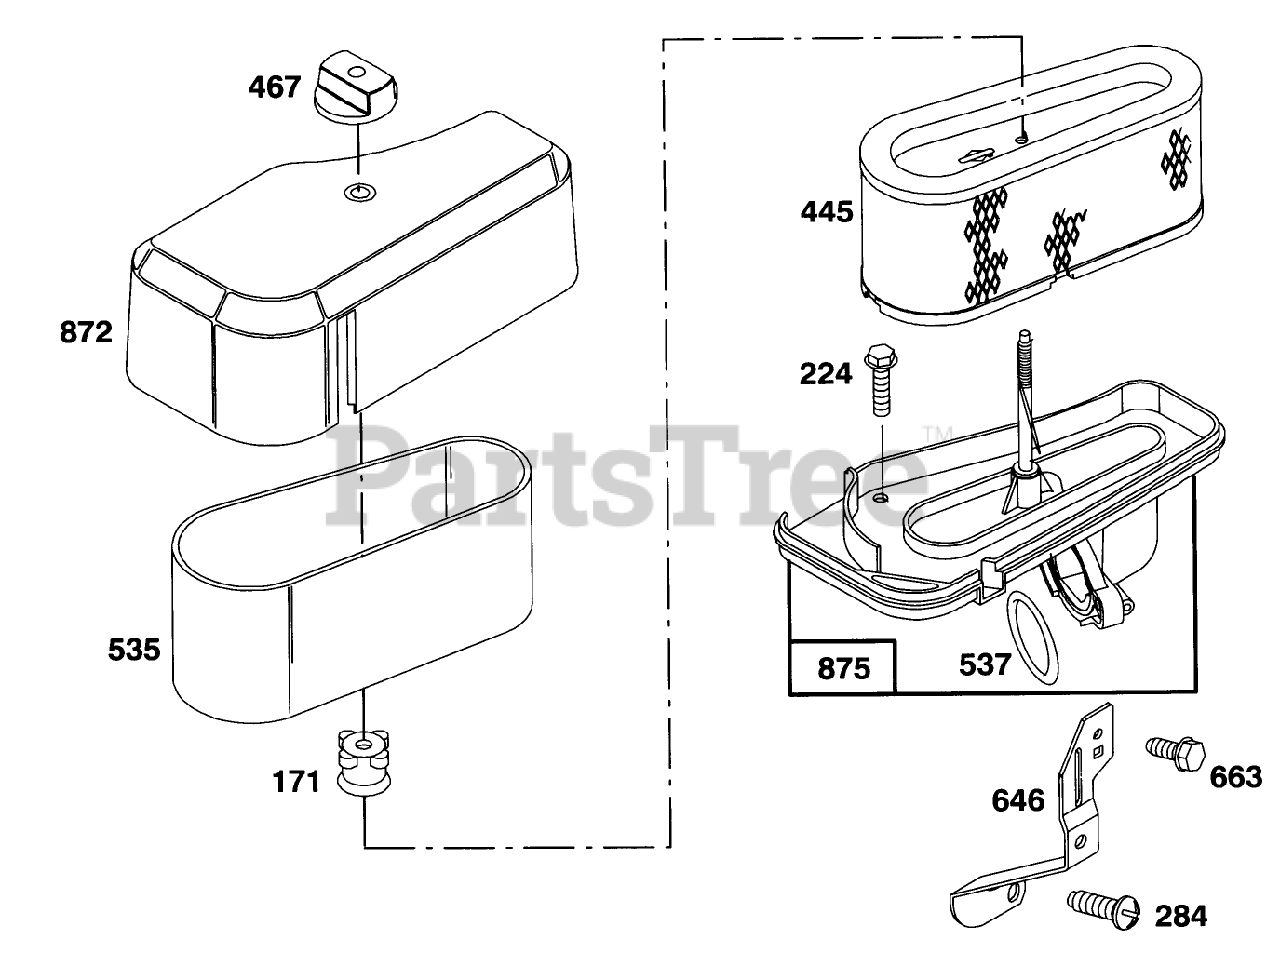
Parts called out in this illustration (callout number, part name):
224	Screw-Sem
284	Screw-Pan Head
445	Filter-Air
535	Filter-Air
537	O-Ring
646	Brace-Air Cleaner
663	Screw
872	Cover-Air Cleaner
875	Base-Air Cleaner
